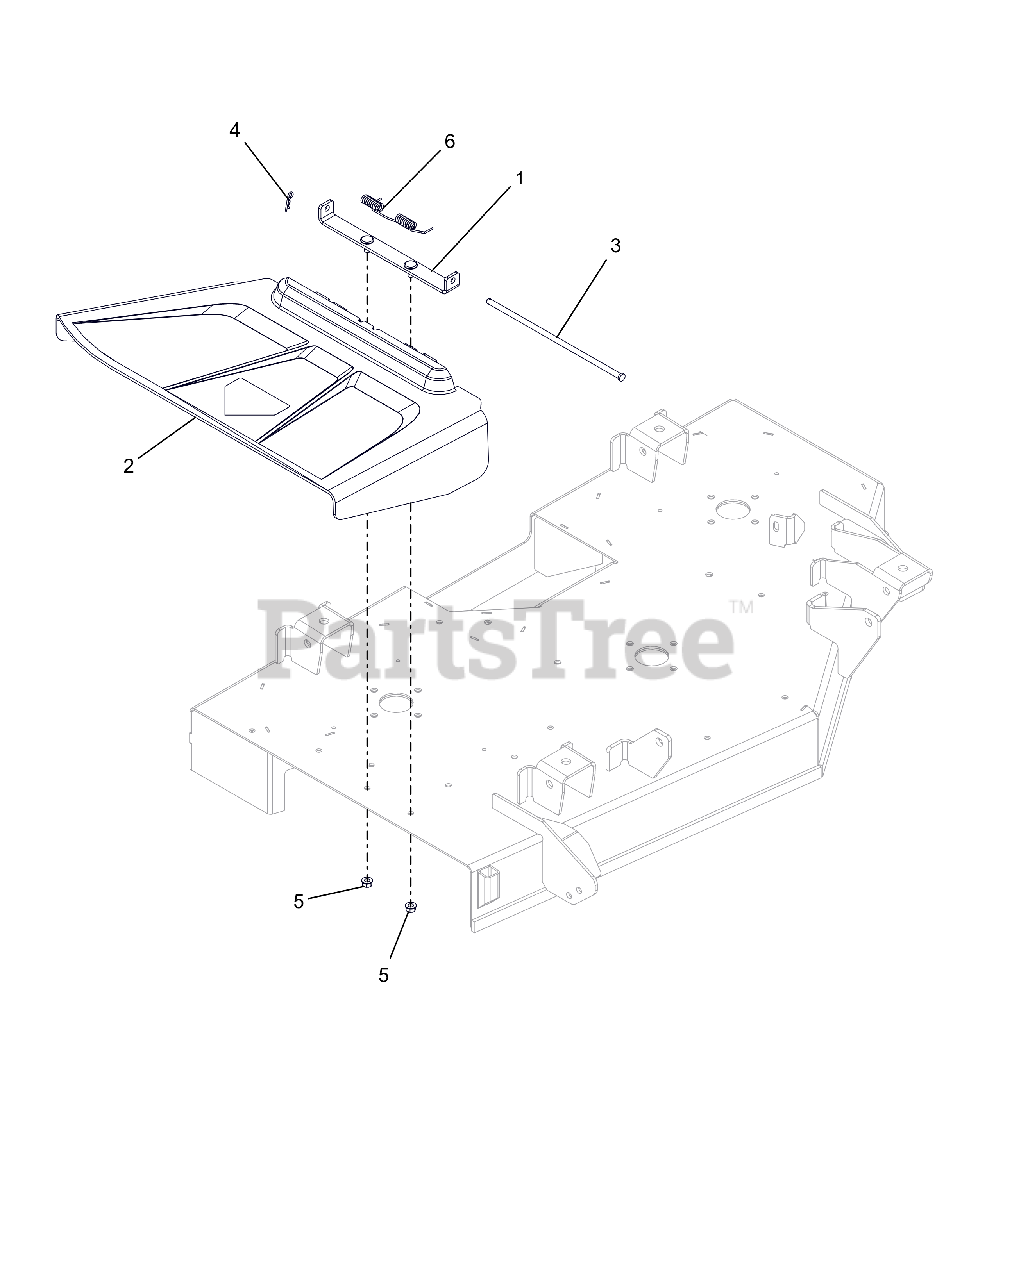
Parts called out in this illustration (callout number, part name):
1	WLDMT, CHUTE MT BRKT
2	CHUTE, SIDE DISCHARGE
3	PIN, 5/16 X 10.5
4	PIN, HAIR #213 .08X1.19 ZCC
5	NUT-LK-TOP-FLG .312-18 GF ZCC
6	SPRING-TORSION
